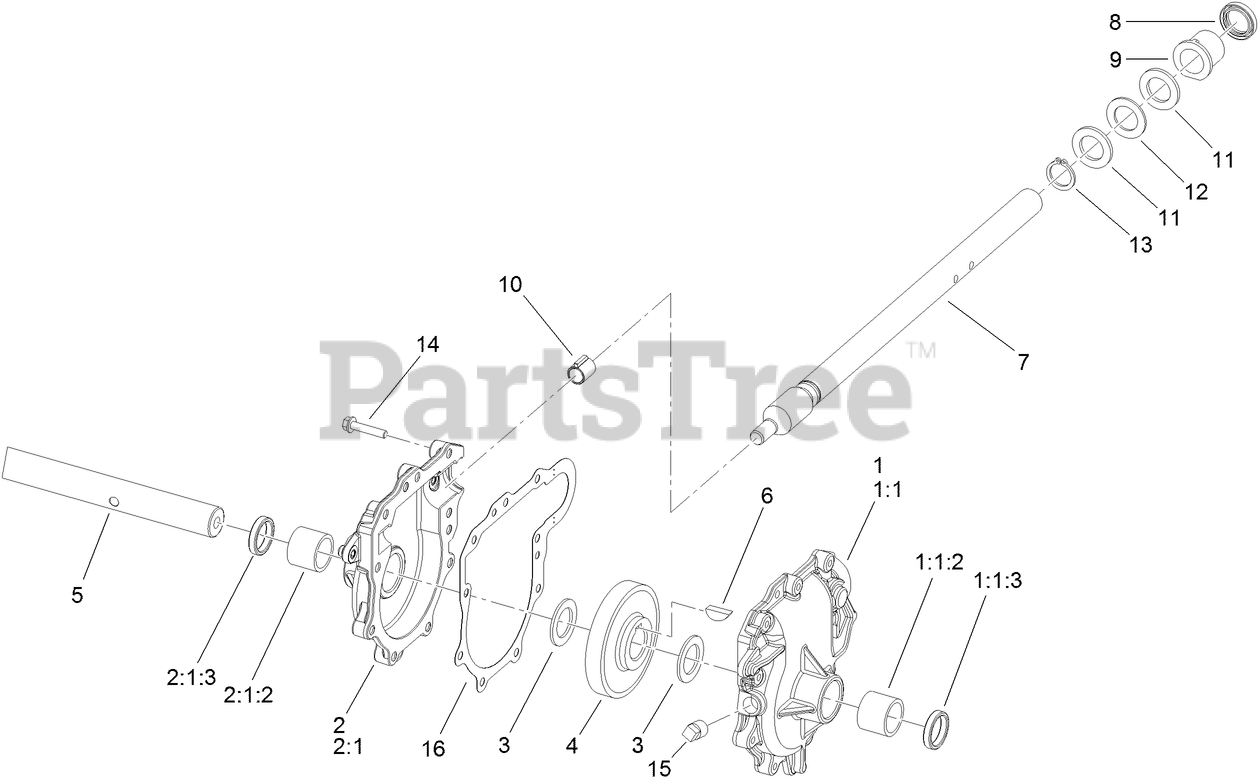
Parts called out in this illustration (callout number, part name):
1	LH AUGER GEARCASE ASM
1:1	Gearcase-Auger, LH
1:1:2	BUSHING-SLEEVE
1:1:3	SEAL-OIL
2	RH AUGER GEARCASE ASM
2:1	Loose Parts Package
2:1:2	BUSHING-SLEEVE
2:1:3	SEAL-OIL
3	WASHER-THRUST
4	GEAR-HELICAL
5	SHAFT-AUGER
6	KEY-WOODRUFF
7	SHAFT-IMPELLER
8	SEAL-OIL
9	BUSHING-INPUT
10	BUSHING-WORM
11	WASHER-THRUST
12	BEARING-THRUST
13	RING-RETAINING, EXT
14	SCREW-HWHTF
15	PLUG-PIPE, SQH
16	GASKET-GEARCASE, AUGER
